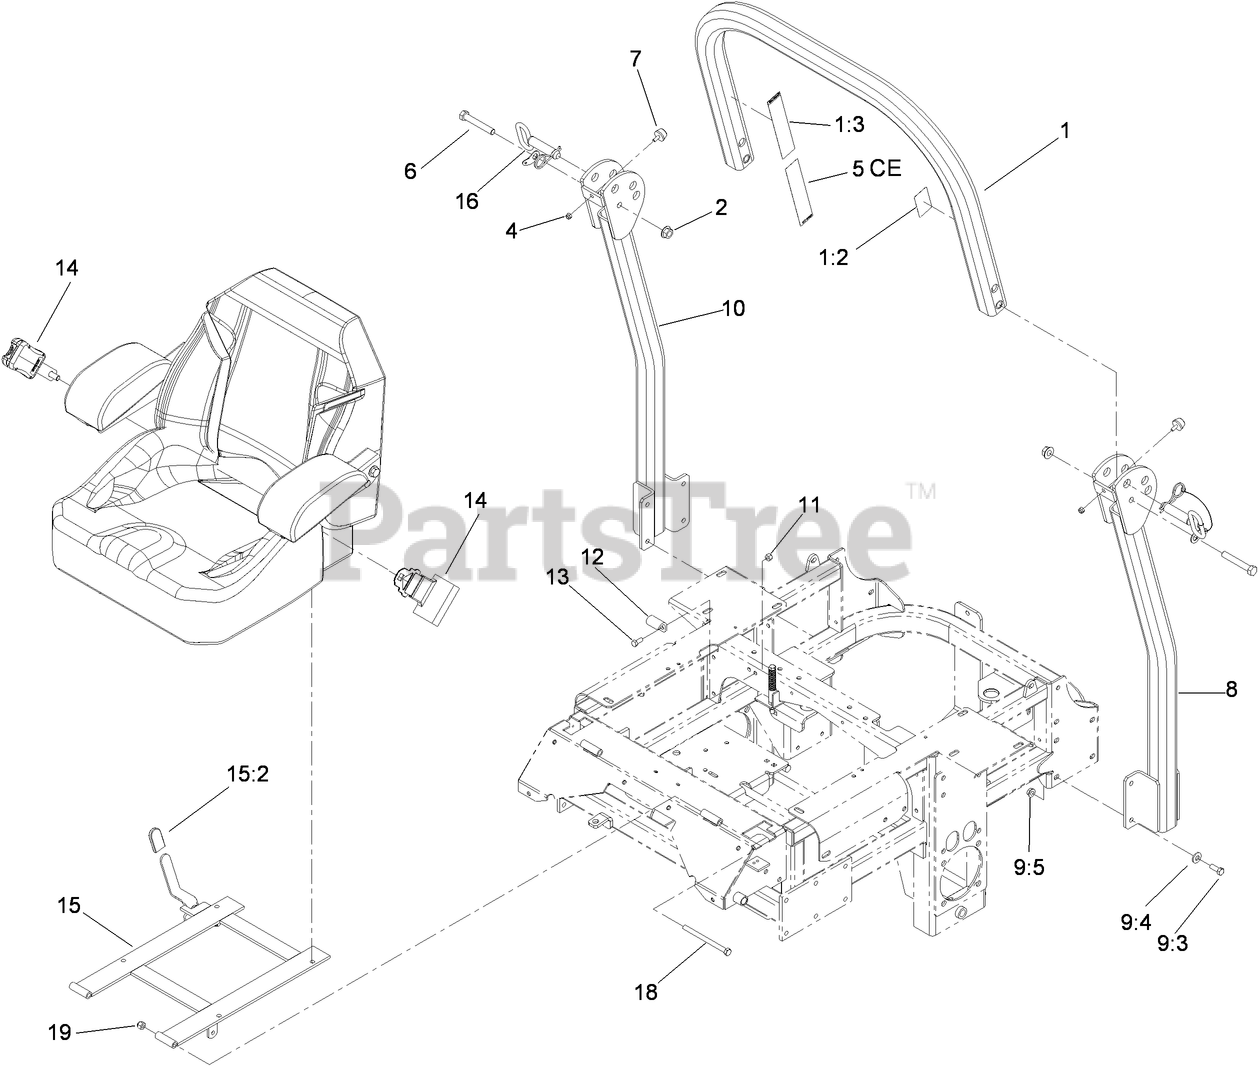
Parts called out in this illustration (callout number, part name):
1	Upper Tube ASM
1:2	DECAL-ROPS
1:3	DECAL-WARNING, FOLDING ROPS
2	NUT-HF
4	NUT-LOCK, NI
5	DECAL-WARNING
6	SCREW-HH
7	BUMPER-RUBBER
8	TUBE-SUPPORT, LH
9	BAG-BOLT, ROPS
9:3	SCREW-HH
9:4	WASHER-BELLEVILLE
9:5	NUT-HHF, WHIZ
10	TUBE-SUPPORT, RH
11	NUT-LOCK, NI
12	Catch-Latch, Seat
13	SCREW-HH
14	SEAT BELT KIT
15	SEAT FRAME AND LATCH ASM
15:2	GRIP-LEVER
16	PIN-FOLD, ROPS
18	SCREW-HH
19	NUT-LOCK, NI
